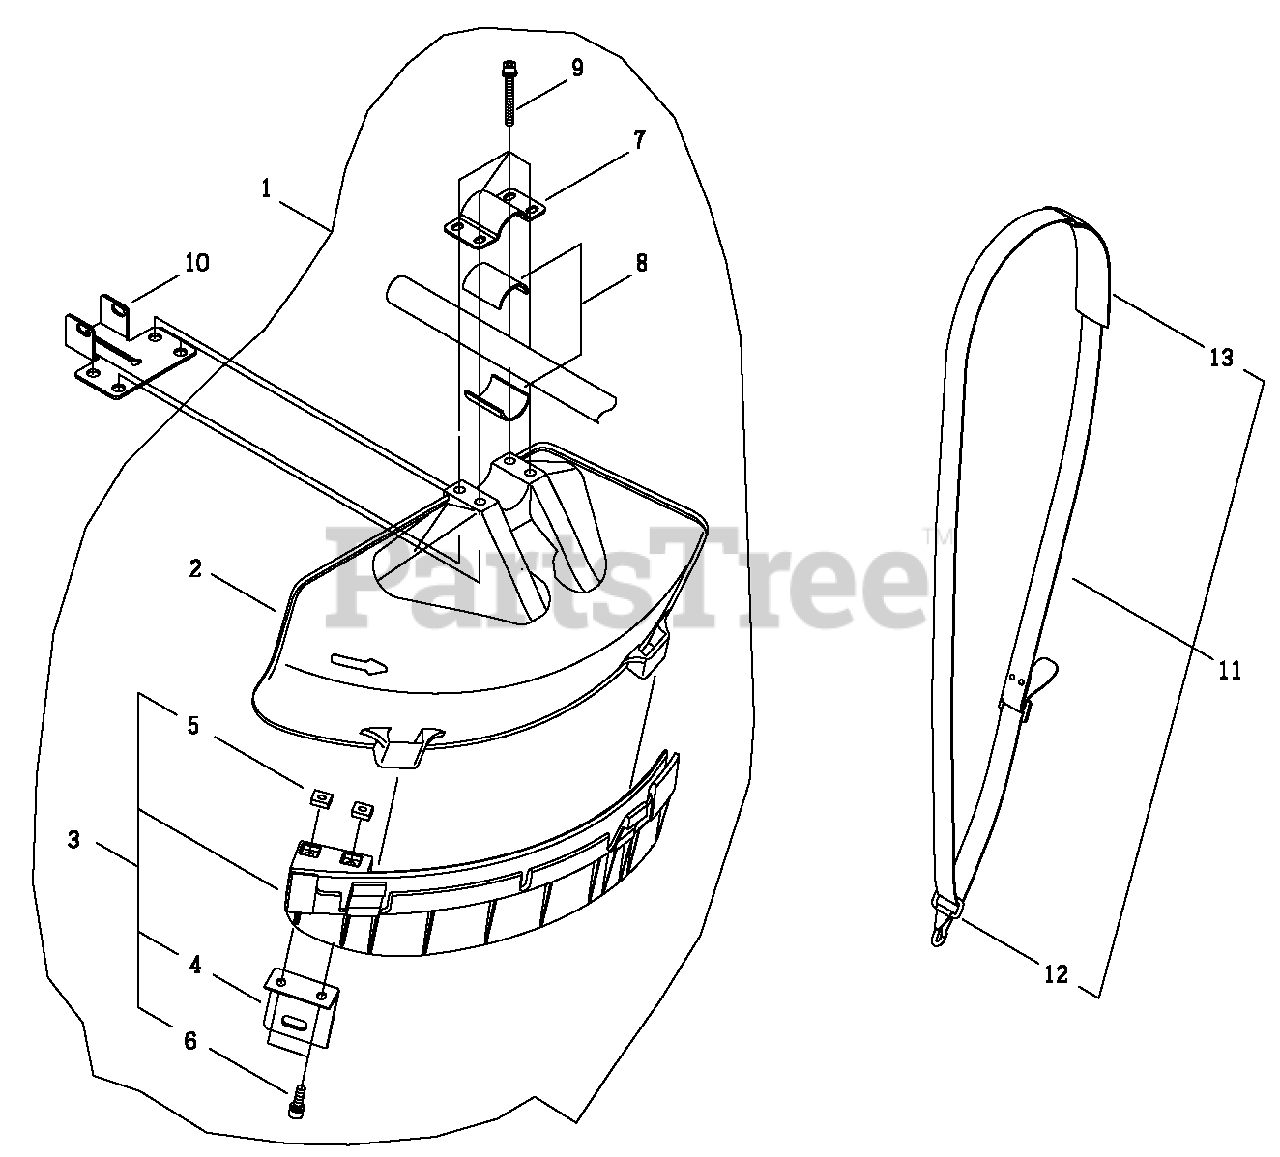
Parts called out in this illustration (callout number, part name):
1	DEBRIS SHIELD KIT
2	SHIELD, DEBRIS
3	SHIELD GUARD KIT
4	KNIFE, TRIMMER LINE
5	NUT - 5
6	SCREW - 5X16
7	CLAMP - UPPER
8	SPACER
9	SCREW - 5X45
10	CLAMP - LOWER
11	SHOULDER STRAP ASSY
12	HOOK
13	PAD, SHOULDER
